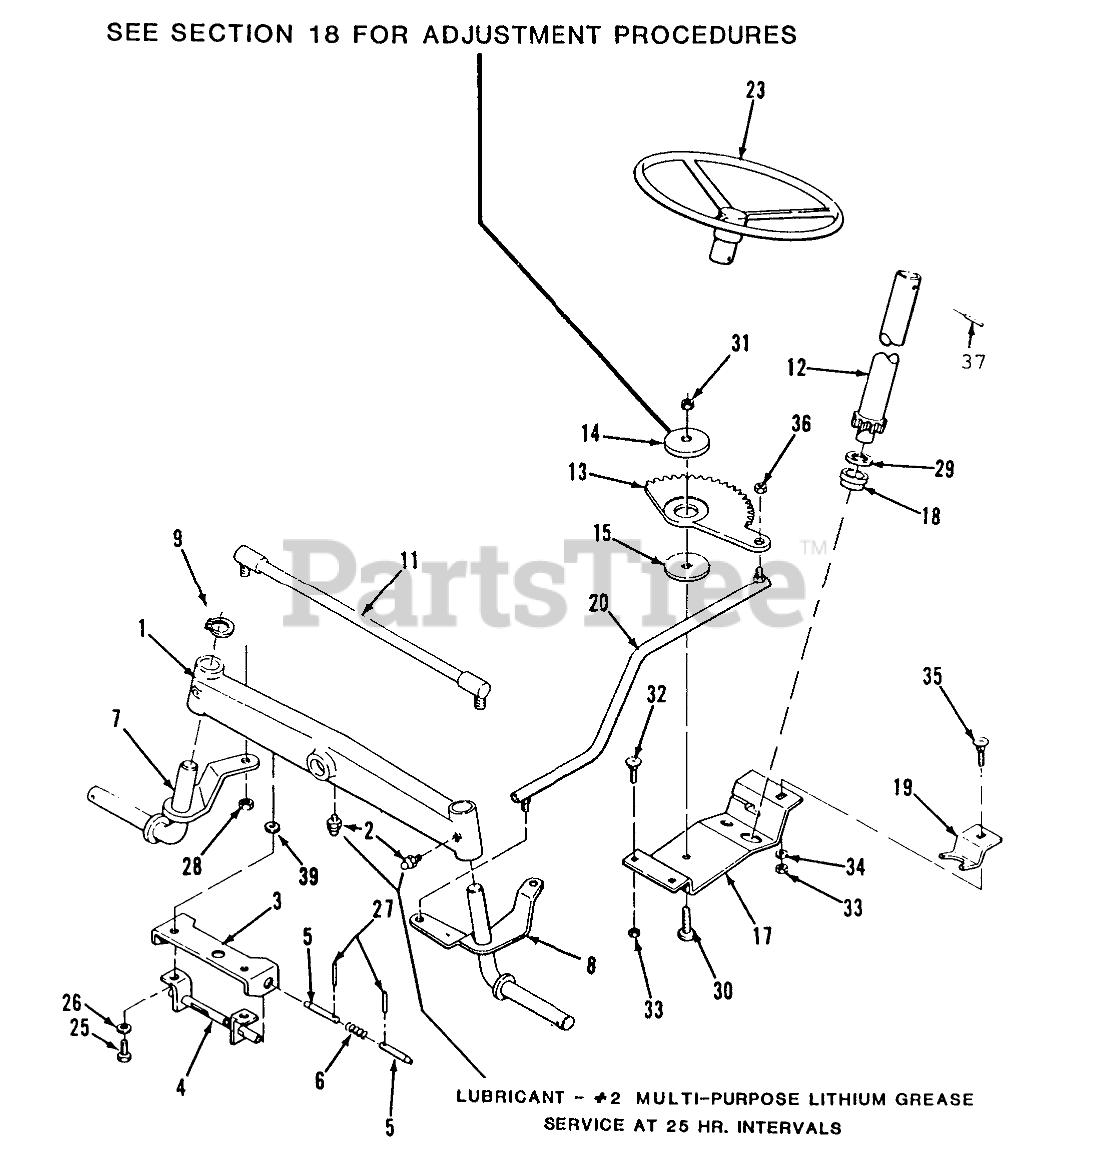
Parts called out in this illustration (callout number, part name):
1	AXLE-FRONT R
2	Zerk
3	BRACKET-SUPPORT R
4	TUBE & BRACKET ASM R
6	SPRING
7	ASSY ARM STEERING R
8	ASSY ARM STEERING R
9	Snap Ring
11	ASS'Y-TIE ROD R
12	ASSY PINION & SHA B
13	GEAR SECTOR
14	BUSHING
15	WASHER-BEARING
17	BRKT-STEERING GEAR
18	BEARING-WHEEL
19	RETAINER R (NS)
20	ASSY BALL JOINT L R
23	WHEEL STEERING
25	HHCS
26	Lockwasher
27	SPIROL PIN
28	Nut-Lock
29	WASHER
30	Bolt-Carriage
32	Bolt
33	Nut
34	WASHER 5/16 SAE
35	Bolt-Carriage
36	NUT-6
37	SPIROL PIN 5/16X13/8
39	WASHER
